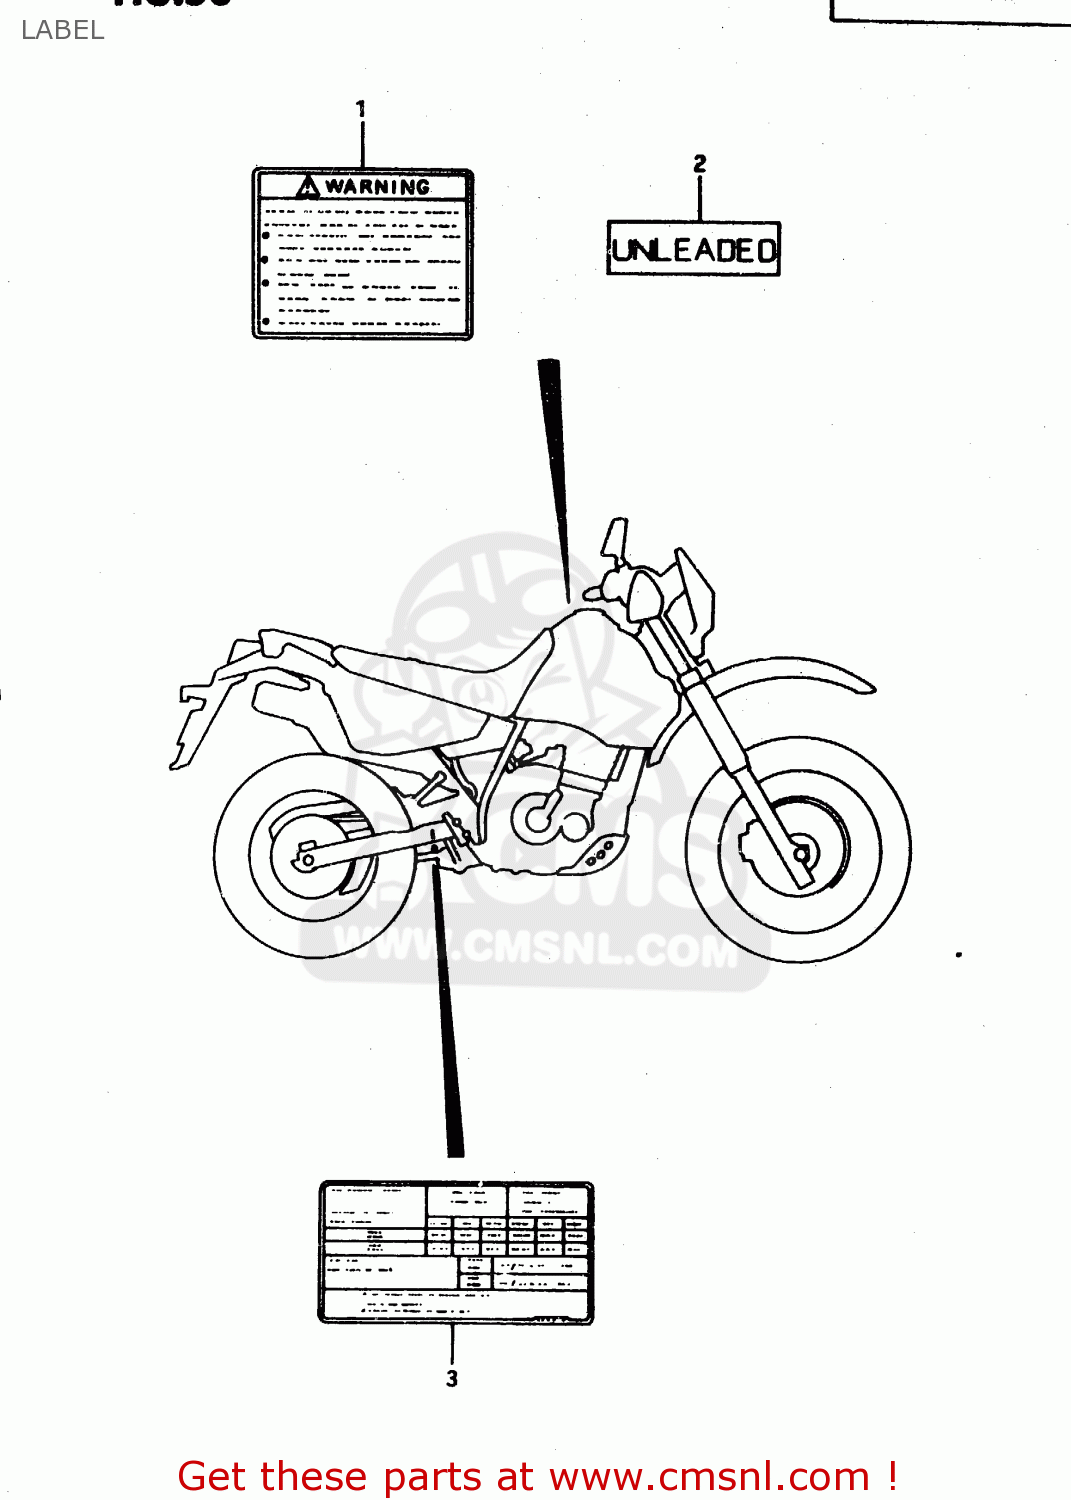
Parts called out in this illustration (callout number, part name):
1	LABEL
2	LABEL,CAUTION
3	LABEL,TIRE AIR PRESSURE
4	MANUAL, OWNER'S
